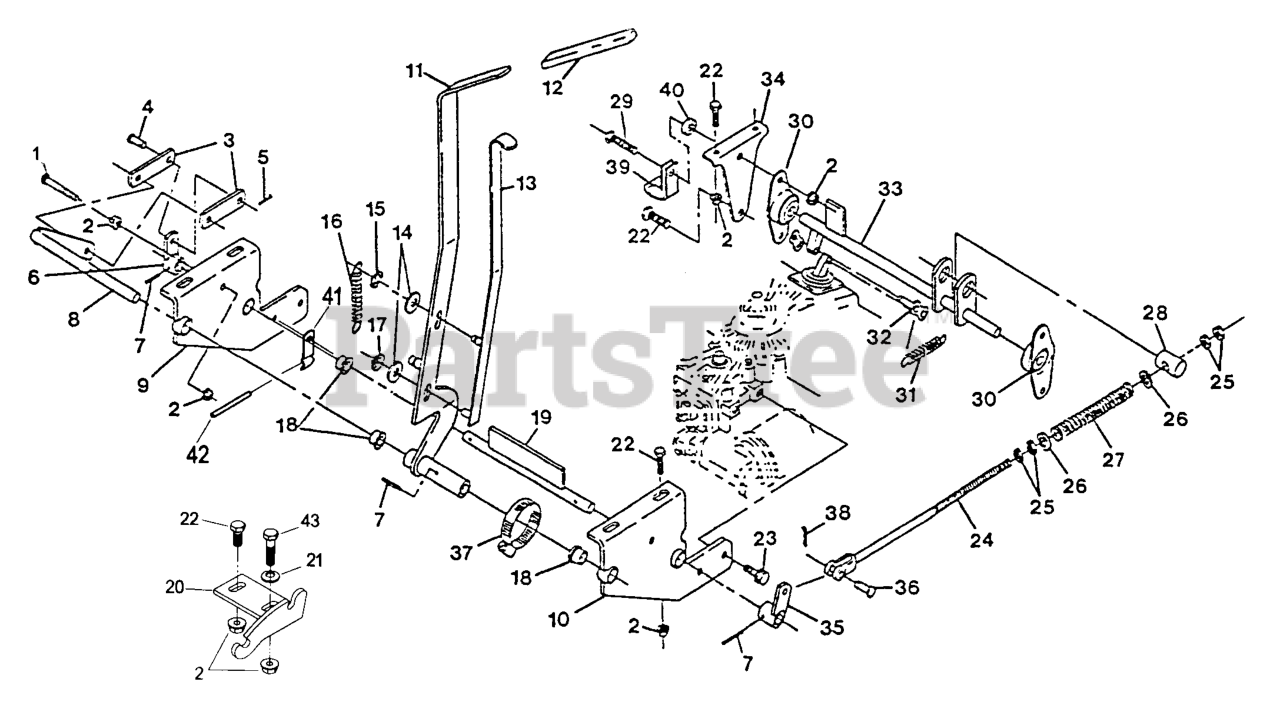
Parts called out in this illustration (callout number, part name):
1	SCREW-HH
3	LINK,BRAKE PLTD
4	PIN-CLEVIS
5	PIN-COTTER
6	WLD,CONTROL ARM
8	PIVOT - BRKT/LEVER
10	WLD,TRANSAXLE SUPPORT RH
12	GRIP-LEVER
14	WASHER-PLAIN
15	RING-RETAINING, EXT
16	SPRING,BRAKE HANDLE
17	NUT,PUSH
18	BEARING-CONTROL
19	WLD,BUTTERFLY
20	WLD,BRAKE QUADRANT
21	WASHER-SPRING
22	SCREW-HH
23	SCREW-HHF
24	LINKAGE,BRAKE
25	NUT-HJ
26	WASHER-FLAT
27	SPRING,COMPRESSION
28	PIN,TRUNION
29	SCREW-HH
30	FLANGE MTG, SIDE
32	LINK,CONNECTING
33	WLD,BRAKE JACKSHAFT
36	PIN-CLEVIS
37	CLAMP-HOSE
38	PIN-COTTER
40	SPACER,CLUTCH ANCHOR
41	SPRING,DUMP VALVE
42	ROLLPIN PLTD
43	SCREW-HH
